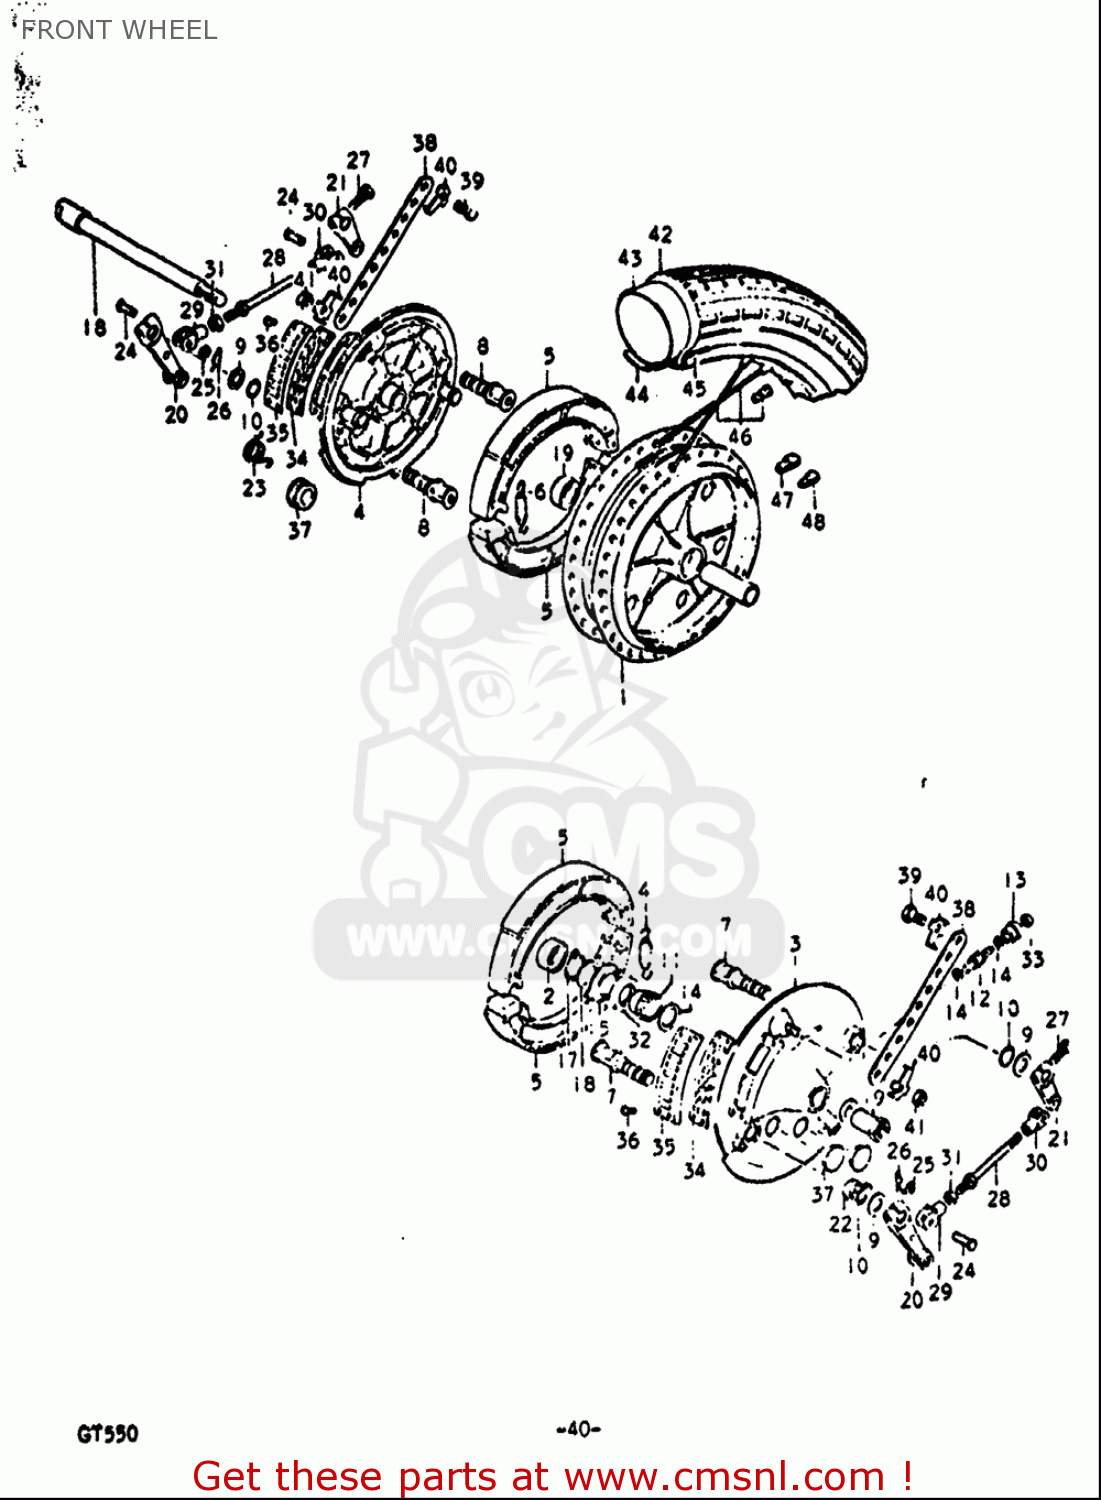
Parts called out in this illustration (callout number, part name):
2	BEARING
5	SHOE SET,FR BRAKE (NAS)
6	SPRING,BRAKE SHOE
9	WASHER(15.5X24X1.6)
10	O RING(D:2.4,ID:14.8)
12	PINION,SPEEDOMETER
13	BUSHING,SPEEDOMETER PINION
14	WASHER(5.1X9X0.4)
15	DRIVER,SPEEDOMETER GEAR
16	WASHER(22.5X27X1)
17	CIRCLIP
22	SPRING
25	WASHER
26	PIN 12X10
27	BOLT
31	NUT
32	SEAL,OIL(26X38X4)
33	SEAL,OIL(6X10X3)
36	SCREW
41	NUT
44	PROTECTOR,WHL INR TUBE
45	RIM,WHEEL
47	BALANCER,WHEEL (30G)
48	BALANCER,WHEEL (B)
